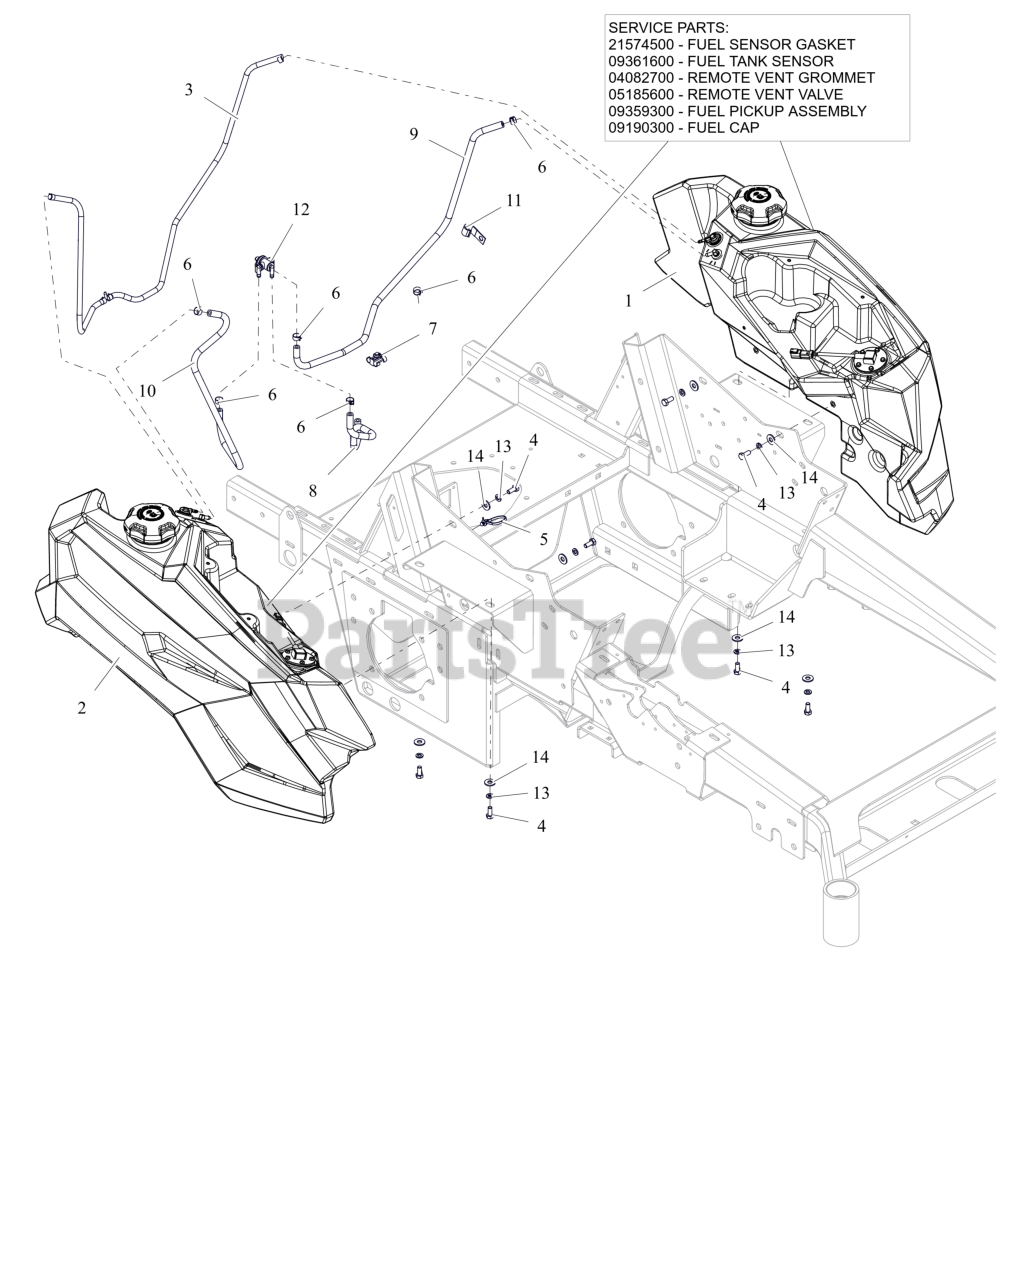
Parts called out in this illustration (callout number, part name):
1	ASM, LH FUEL TANK
2	ASM, RH 421 FUEL TANK
2	FUEL TANK SENSOR GASKET
2	FUEL TANK SENSOR
2	GROMMET, REMOTE VENT NITRILE
2	VALVE, COMBINATION VENT 3/16
2	FUEL PICKUP ASSEMBLY
3	ASM, KAWASAKI EFI VAPOR LINE
4	BLT,HEX .31-18X.75 G5 ZCC
5	CABLE TIE W/ TREE (.25 HOLE)
6	CLAMP, FUEL LINE
7	CLIP, T, .38-.50
8	HOSE, .25 LOW-PERM BULK GAS
9	HOSE, .25 LOW-PERM BULK GAS
10	HOSE, .25 LOW-PERM BULK GAS
12	VALVE, FUEL - WITH MAGNET
13	WSHR,LK-REG .312X.078 ZCC
14	WSHR,FLT .375X.875X.083 ZCC
